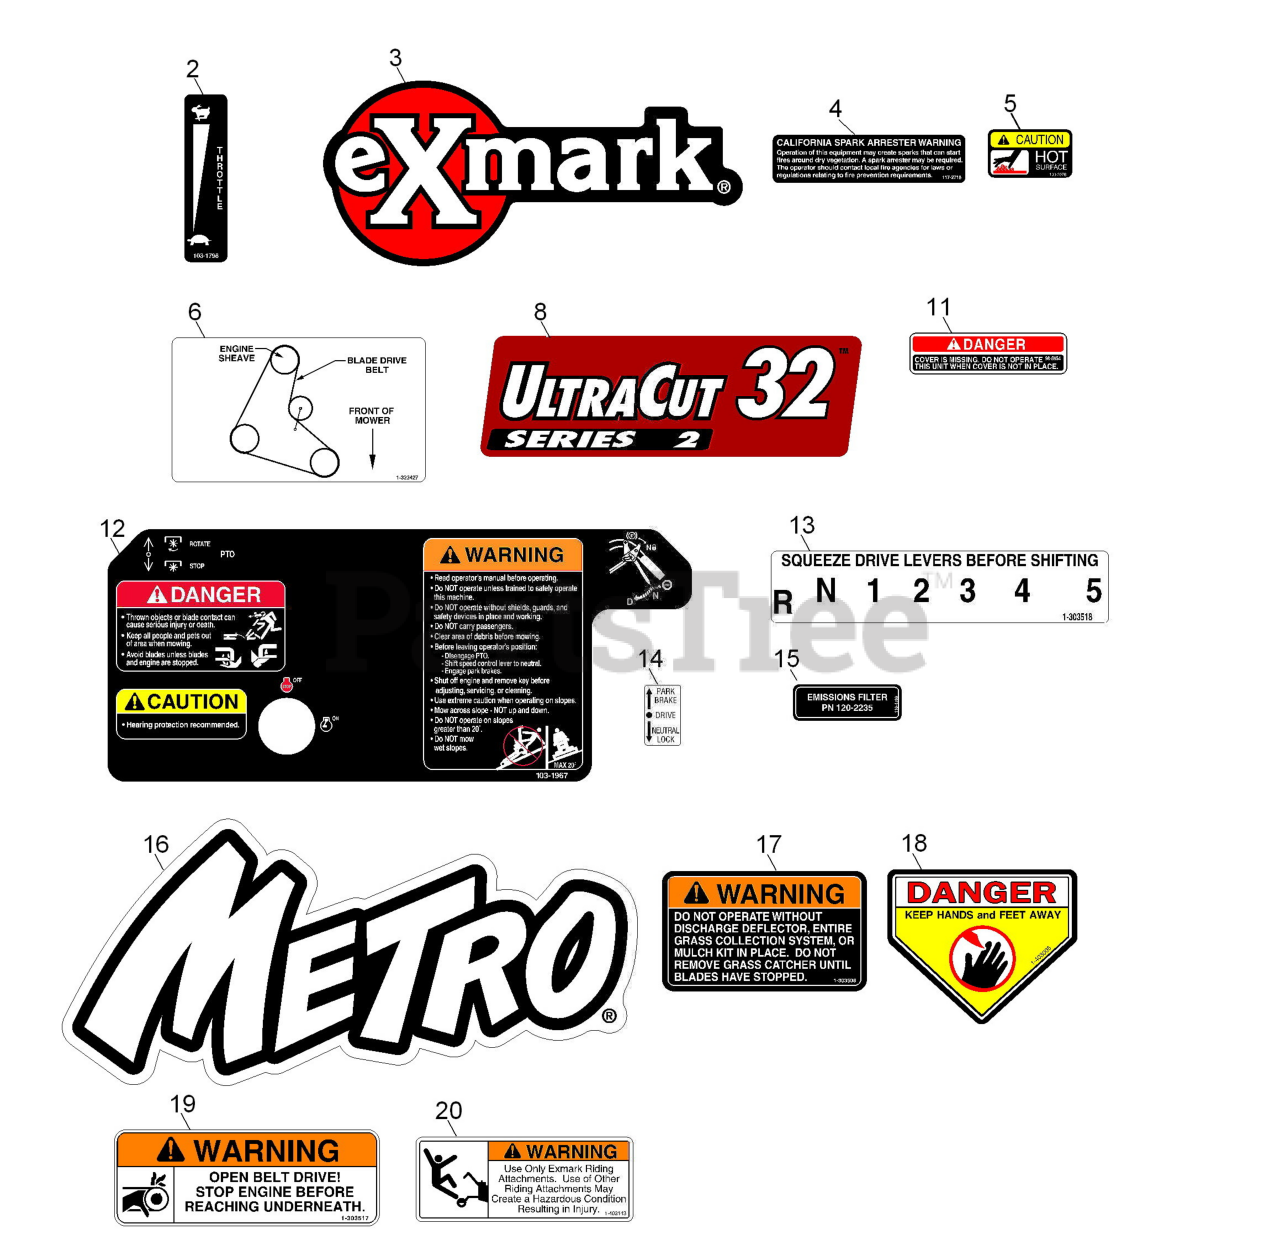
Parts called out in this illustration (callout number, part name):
2	DECAL,THROTTLE ONLY
3	DECAL,EXMARK LOGO
4	DECAL-ARRESTER, SPARK
5	DECAL-CAUTION
6	DECAL,BELT ROUTING 32/36
8	DECAL-ULTRACUT 32 SERIES
11	DECAL-COVER, MISSING
12	DECAL,CONSOLE
13	DECAL,SHIFTER
14	DECAL,NEUTRAL/BRAKE
15	DECAL-FILTER, EMISSIONS
16	DECAL,METRO MODEL
17	DECAL-WARNING, DISCHARGE
18	DECAL-DANGER
19	DECAL,BELT DRIVE
20	DECAL,SULKY WARNING
